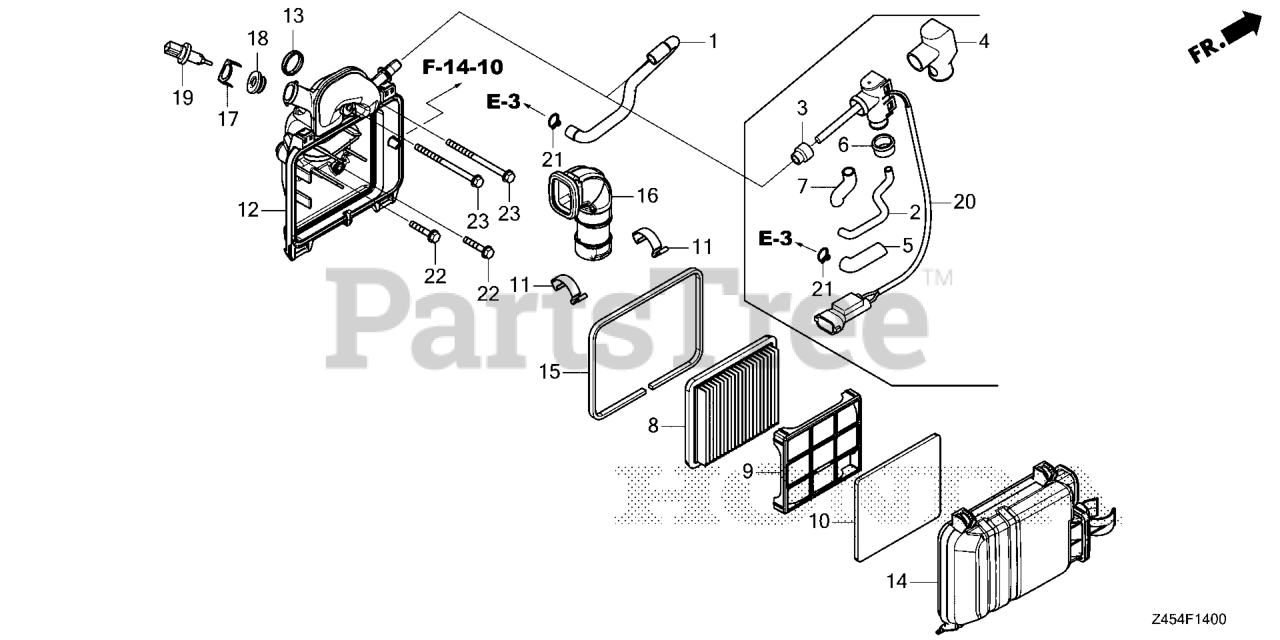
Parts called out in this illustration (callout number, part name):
1	TUBE, BREATHER
8	ELEMENT, AIR CLEANER
9	GRID, AIR CLEANER
10	FILTER (OUTER)
11	CLIP, AIR/C
12	CASE COMP, A/CLNR
13	O-RING, AIR CLEANER
14	COVER COMP, A/CLNR
15	SEAL, AIR/C COVER
16	TUBE, AIR/C
19	SENSOR, TEMPERATURE
21	CLAMP B, TUBE (12.5MM)
22	BOLT, FLANGE (6X32)
23	BOLT, FLANGE (6X90)
